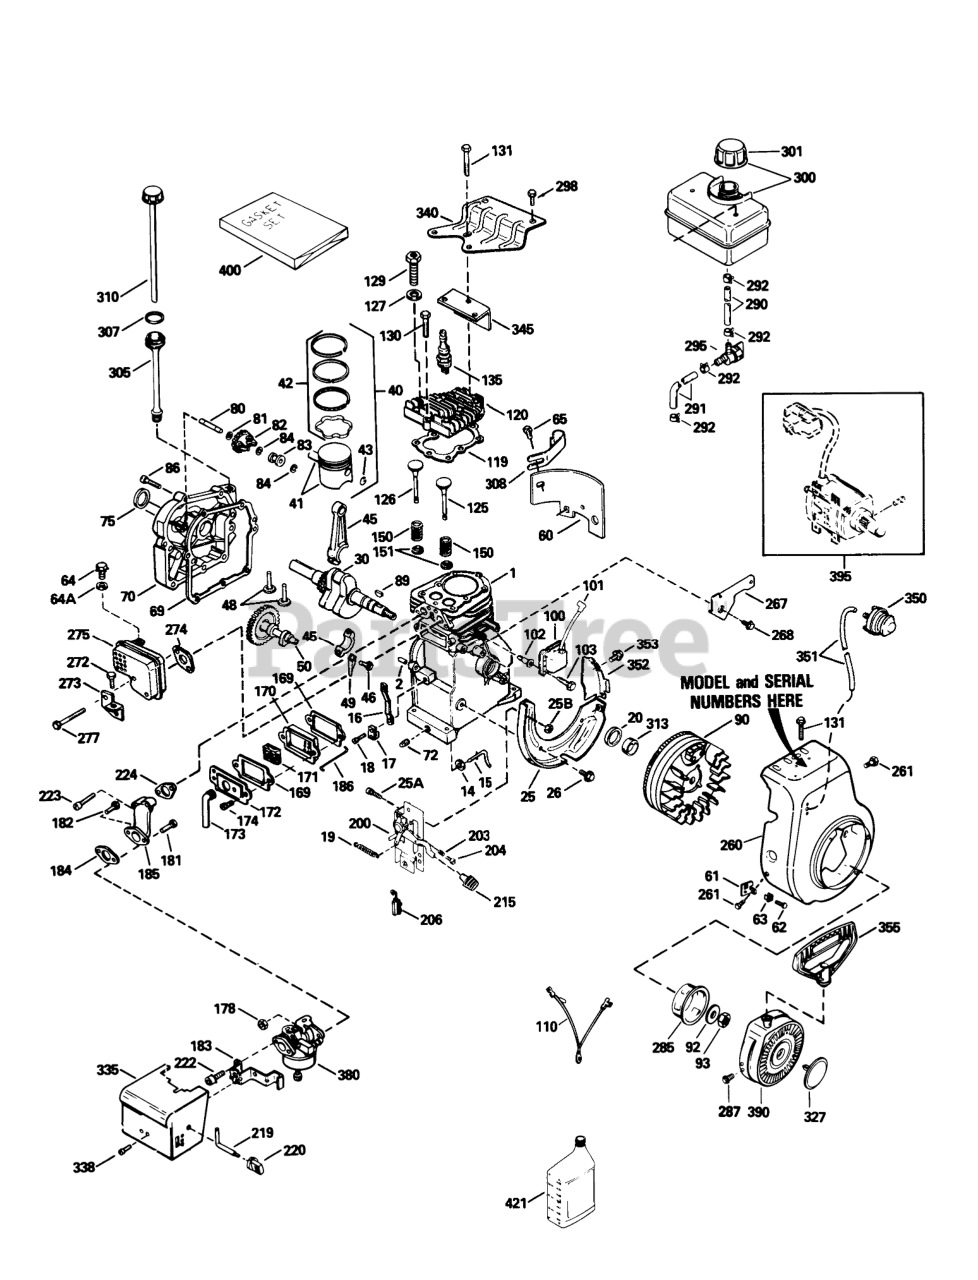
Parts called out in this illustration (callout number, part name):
1	Cylinder Assembly (Incl. Ref. #2, 20 & 72)
2	Pin-Dowel
14	Washer-Flat
15	Rod-Governor
16	Lever-Governor
17	Clamp-Lever, Governor
18	Screw
19	Spring-Extension
20	Seal-Oil
25	Baffle-Blower Housing
25A	Screw
25B	Nut-Lock
26	Screw (1/4-20x19/32)
30	Crankshaft ASM
40	Piston-Pin & Ring Assy. Std. (Incl. Ref. #41-43)
41	Piston & Pin Assy. Std. (Incl. Ref. #43)
42	Ring Set-Piston Std.
43	Ring-Retaining, Piston Pin
45	Connecting Rod Assembly (Incl. Ref. #46 & 49)
46	Bolt-Rod, Connecting
48	Lifter-Valve
49	Dipper-Oil
50	Camshaft
60	Extension-Blower
61	Bracket
62	Screw (8-32 x 3/8)
63	Grommet
64A	Washer
69	Gasket-Cover, Cylinder
70	Cover-Cylinder (Incl. Ref. #75 & 80)
72	Plug-Drain, Oil (SQH 1/4-18)
75	Seal-Oil
80	Shaft-Governor
81	Washer-Flat
82	Gear-Governor (Incl. Ref. #81)
83	Spool-Governor
84	Ring-Retaining
86	Screw (1/4-20 x 1-1/4)
89	Key-Flywheel
90	CLAMP
92	Washer-Belleville
93	Nut-Flywheel
100	Solid State
101	Cover-Spark Plug
102	Stud
103	Screw
110	Wire-Ground
119	Gasket-Cylinder Head
120	Head-Cylinder (Incl. Ref. #131)
125	Valve-Exhaust Standard (Incl. Ref. #151)
126	Valve-Intake Standard (Incl. Ref. #151)
127	Washer-Flat
129	Screw ( 5/16-18 x 1-1/2)
130	Screw
131	Screw (5/16-18 X 2)
135	Spark Plug-Resistor (R J19 L M)
150	Spring-Valve
151	Cap-Valve, Spring
169	Gasket-Cover, Valve
170	Body-Breather
171	Element-Breather
172	Cover-Breather
173	Tube-Breather
178	Nut and Lock Washer (1/4-28)
181	Screw (1/4-28 x 7/8)
182	Screw (1/4-28 x 1-11/16)
183	Bracket-Choke
184	Gasket
185	Pipe-Intake
186	Link-Governor to Throttle
200	Control Assembly (Incl. Ref. #25A, 25B, 203, 204 & 206)
203	Spring-Compression
204	Screw
206	Terminal
215	Knob-Control
219	Rod-Choke
220	Knob-Control
222	Screw (10-32 x 1/2)
223	Screw (1/4-20 x 1-19/32)
224	Gasket-Intake
260	Housing-Blower
261	Screw
267	Bracket-Hold Down
268	Screw (10-24 x 9/16)
272	Screw (10-24 x 3/8)
273	Bracket-Cover, Carburetor
274	Gasket-Exhaust
275	Muffler (Incl. Ref. #274)
277	Screw-Fil. Hd.
285	Cup-Starter
287	Screw, Hex Hd.
290	Line-Fuel (8.62)
291	Line-Fuel
292	Clamp-Line, Fuel
295	Valve-Shut Off, Fuel
298	Screw (1/4-15x7/8)
300	Tank Assembly-Fuel (Incl. Ref. #292 & 301)
301	Cap-Fuel
305	Tube-Fill, Oil
308	Clip-Tube, Fill
310	Dipstick
327	Plug Starter
335	Cover-Carburetor
338	Screw (8-32 X 5/16)
340	Plate-Fuel Tank
345	Baffle-Heat
350	Primer-Asm
351	Line-Primer
352	Extension-Baffle
353	Screw, Hex Hd.
355	Handle-Starter, Mitten Grip
380	Carburetor (Incl. Ref. #184)
390	Rewind Starter
395	Motor-Electric Starter
400	Gasket Set
421	Oil-Engine (SAE 5W30)
